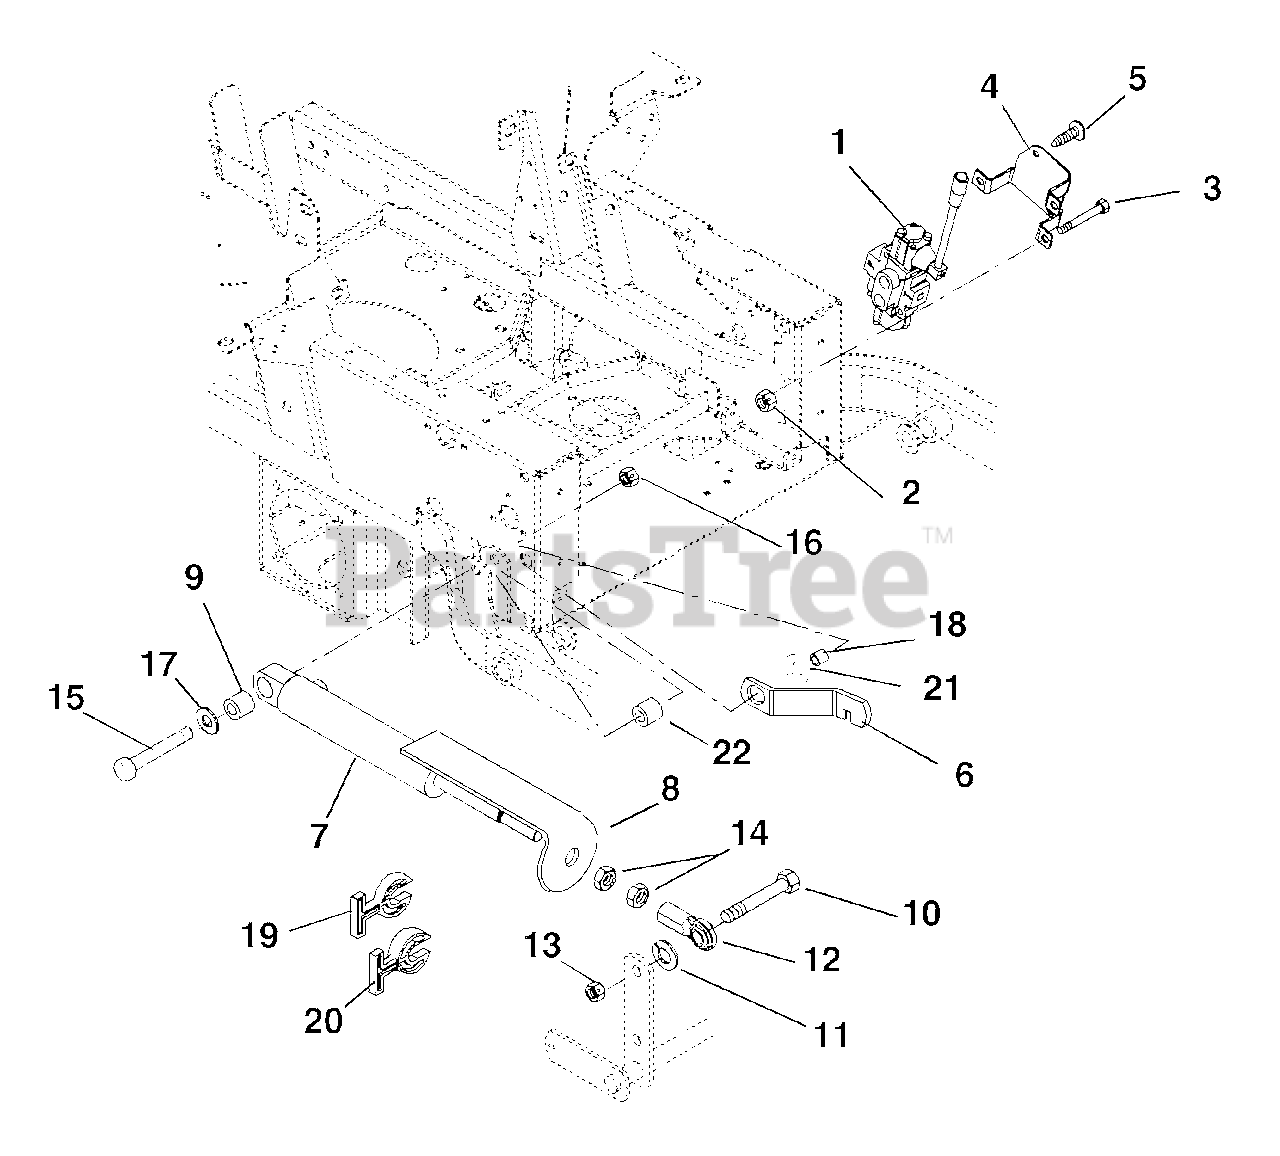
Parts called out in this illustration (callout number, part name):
1	VALVE, HYDRAULIC
2	@NUT-LK-TOP-FLG .31-18 YWZC
3	@BLT-HEX .31-18X2.25 GR5 YWZC
4	VALVE MOUNTING BRACKET -BLACK
5	@SCR-TAP .38-16X.50 HWH TR YWZ
7	CYLINDER - HYDRAULIC LIFT
8	STRAP, CUT INDICATOR/GUARD
9	BUSHING, .516X1.000X1.050 LG
10	BLT-HEX .62-11X2.25 YWZC GR8
11	@WSHR-LK .62X.156 REG YWZC
12	ROD END, 5/8 RH - FEMALE
13	@NUT-LK-CTR .62-11 YWZC
14	NUT-JAM .625-18 YWZC
15	POST, CYLINDER STOP
16	@NUT-LK-TOP-FLG .50-13 YWZC
17	WSHR-FL-STL .515X1.625X.250 YZ
18	BSHG-FLG .515X.750X.285X1.120
19	STOP, CYLINDER .34 THK
20	STOP, CYLINDER .680 THK
21	WASHER-WAVE .760X1.120X.080
22	SPACER .516X1.000X.875
